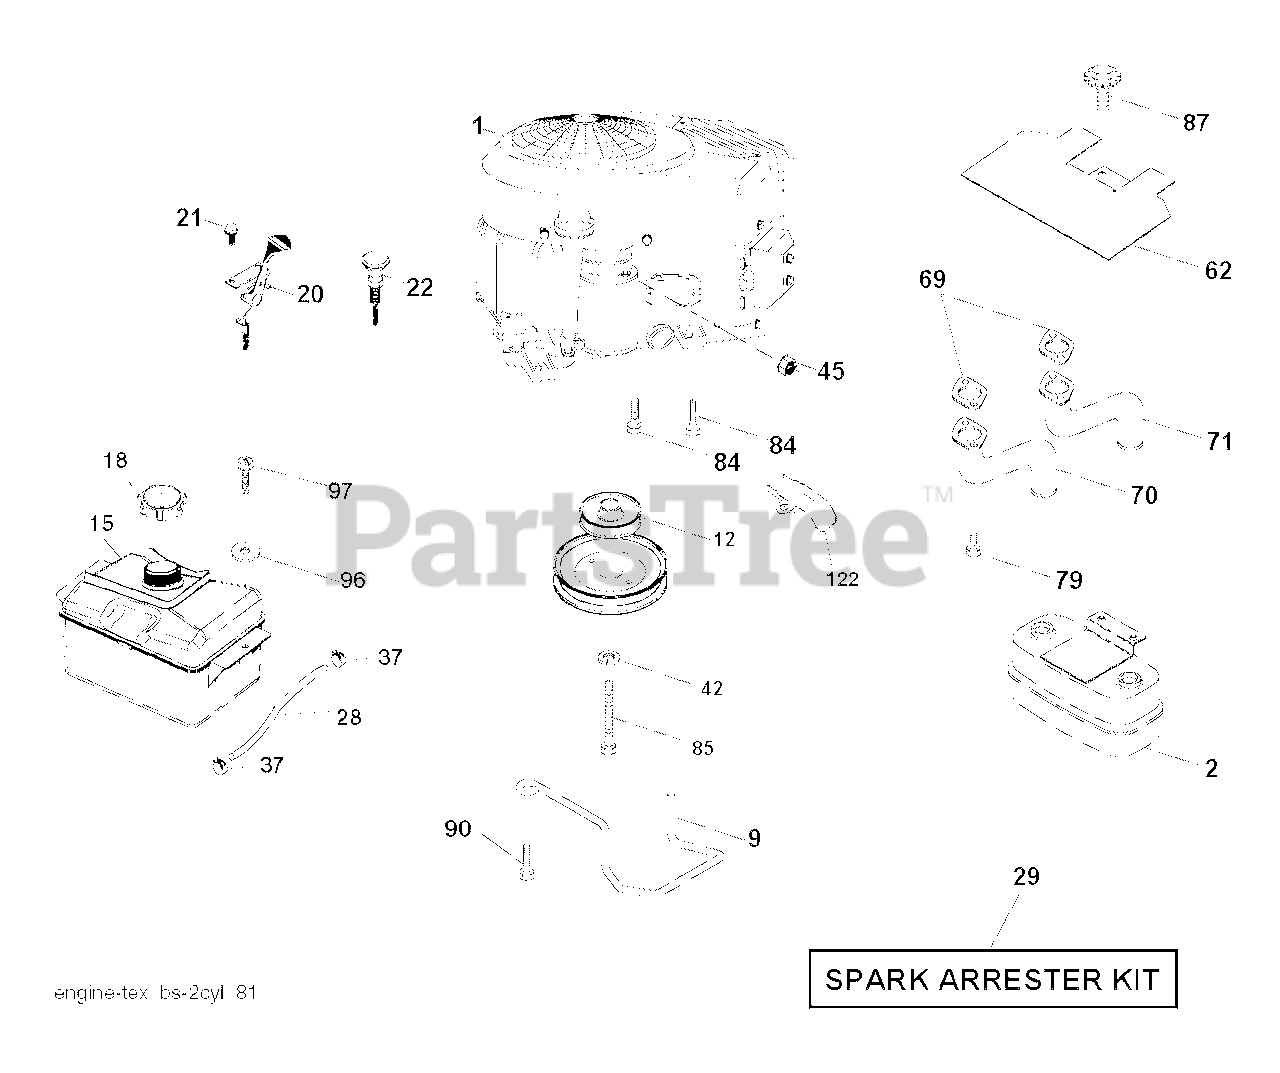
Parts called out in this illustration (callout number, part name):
2	MUFFLER.TWIN.CYL.LOW.TONE
9	KEEPER.BELT.ENGINE.4.2
12	PULLY ENGINE
15	TANK FUEL FRT 1.5 GAL
18	CAP ASM.FUEL.2.25"FR.
20	THROTTLE CABLE
21	SCREW.#10 X 0.750.BOS THREAD
22	CONTROL CHOKE
29	ARRESTER SPARK (OPTIONAL)
42	LOCKWASHER
45	NUT
62	SHIELD.HEAT.MUFFLER
69	GASKET.MUFFLER
70	EXHAUST TUBE LH *SUBS/2*
71	EXHAUST TUBE RH
79	SCREW.SOCKET.HEAD.5/16-18
85	BOLT HEX 7/16-20X4-1/4"
87	BOLT, 5/16-18 X 1 3/4
90	SCREW 3/8-16X1
97	SCREW HEXWSHR 1/4-20X3/4
122	EXTENSION DRAIN OIL
